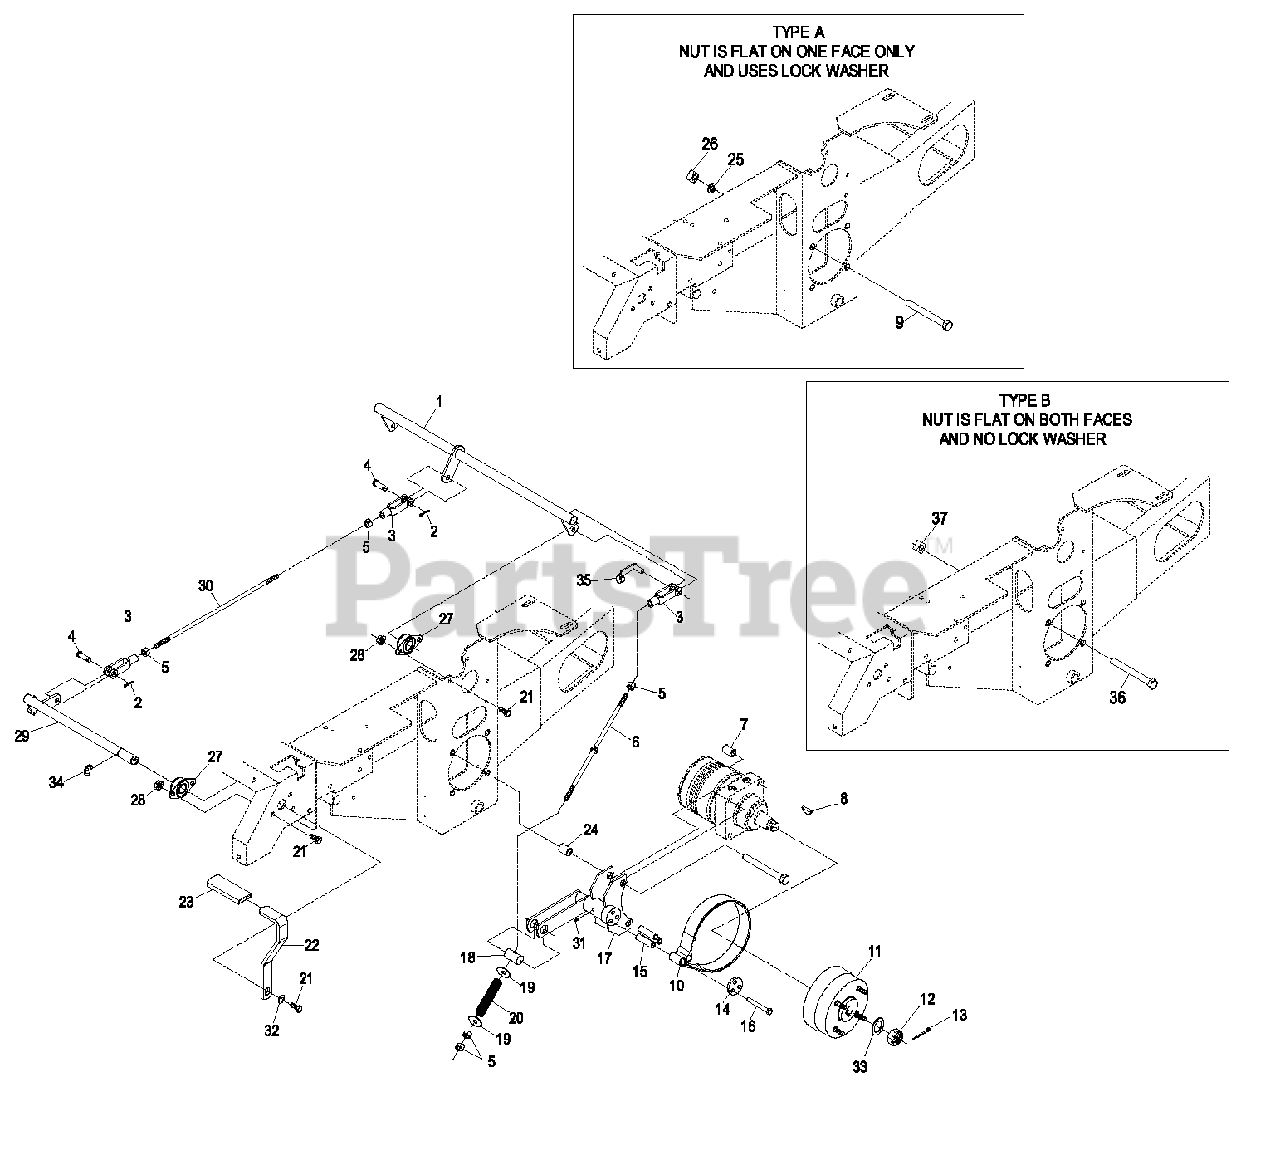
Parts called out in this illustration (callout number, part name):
1	CRANK-BRAKE, PARK
2	PIN-COTTER
3	YOKE-LINKAGE, BRAKE
4	PIN-CLEVIS
5	NUT-HEX
6	ROD-BRAKE
7	SPACER-WHEEL
8	KEY-WOODRUFF
9	SCREW-HH
9	SCREW, HH
10	BAND,BRAKE
11	WHEEL HUB ASM
11	STUD-WHEEL
13	PIN-COTTER
14	RETAINER-BAND, BRAKE
16	SCREW-HH
17	BRACKET-BRAKE
18	PIN-TRUNION
19	WASHER-FLAT
20	SPRING-BRAKE
21	SCREW-HH
22	ASM,BRAKE HANDLE W/ GRIP
23	GRIP-LEVER
24	SPACER-WHEEL
25	WASHER-LOCK
27	BEARING-FLANGE, SIDE
28	NUT-HHF, WHIZ
29	SHAFT-BRAKE, PARKING
30	LINKAGE-HANDLE, BRAKE
31	FITTING-GREASE
32	WASHER-BELLEVILLE
33	WASHER-SPACER
35	PIN-SPRING, CLEVIS
36	SCREW-HH
37	NUT-SQUARE, SPECIAL
